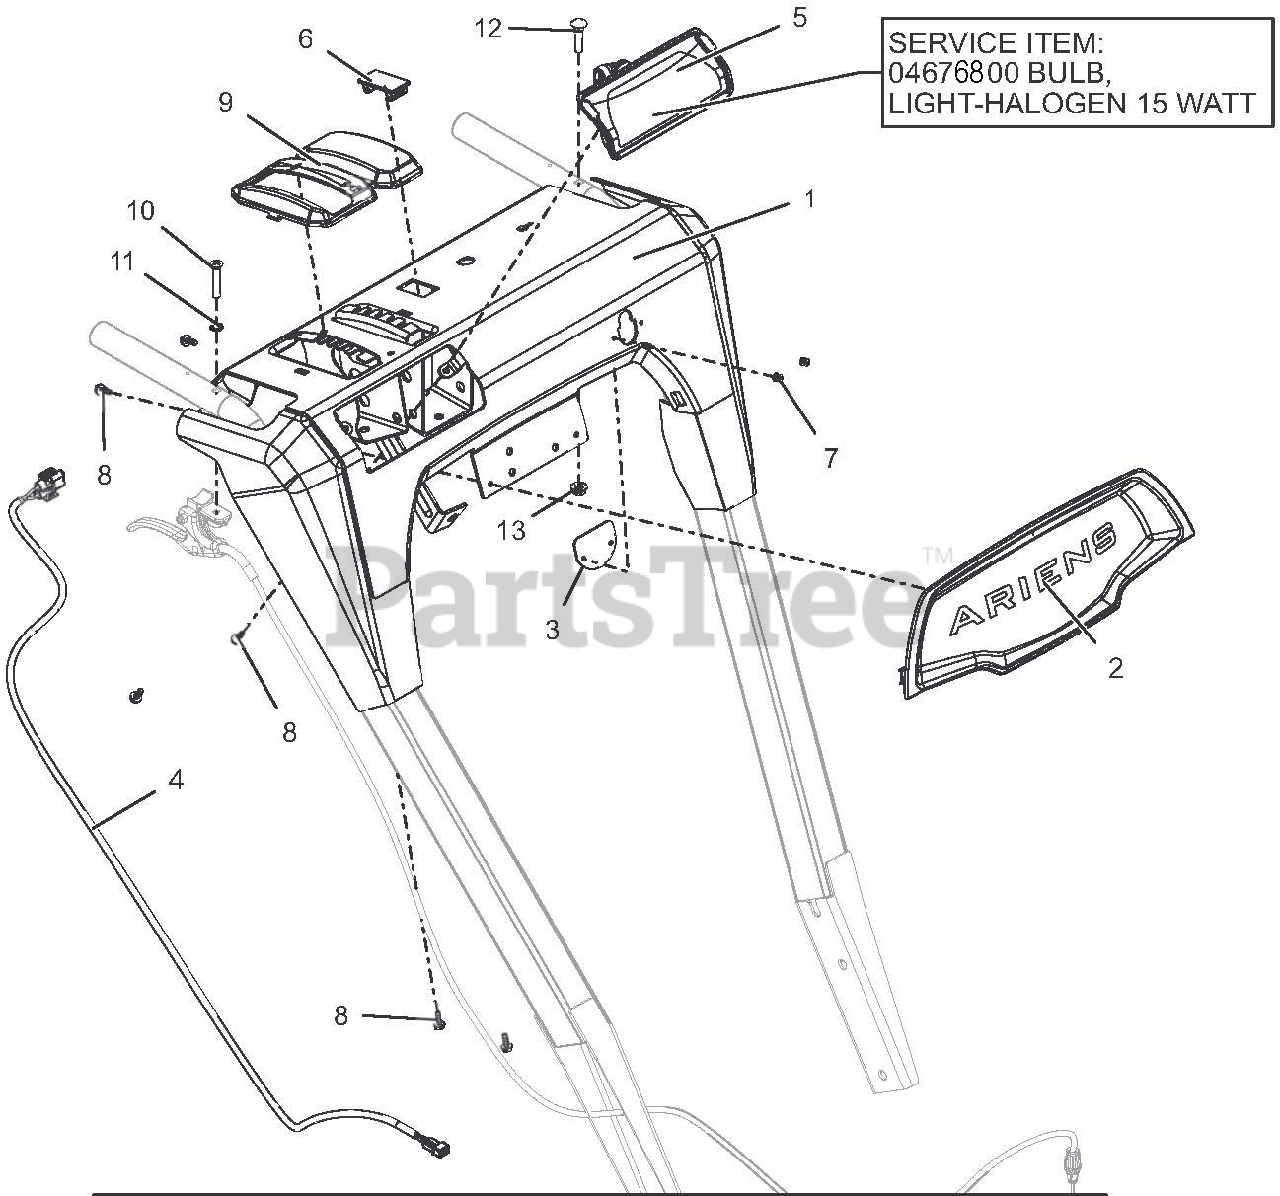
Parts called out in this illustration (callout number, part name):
1	PANEL, DASH - W/CTR DECAL
2	BEZEL, DASH - ARIENS LG DASH
3	COVER, DASH BRKT, BRUSH
4	HARNESS, LIGHT - DELUXE
5	HEADLIGHT ASY, HOLO 15W 2 SHOT
5	BULB, LIGHT-HALOGEN 15 WATT
6	PLUG,DASH PANEL
7	RVT-POP #43 .125X.313 STL ZINC
8	SCR-TAP #10X.50 BOSS INDHXHD
9	BEZEL, SHIFT - FRICTION BRUSH
10	SCR-MCH .25-20X1.50 OVAL HD
11	WSHR-LK-INT .250 TH TYA
12	BLT-RDHDXLSQNK.25-20X1.25 G5ZC
13	@NUT-LK-CTR-FLG .25-20 YWZC
